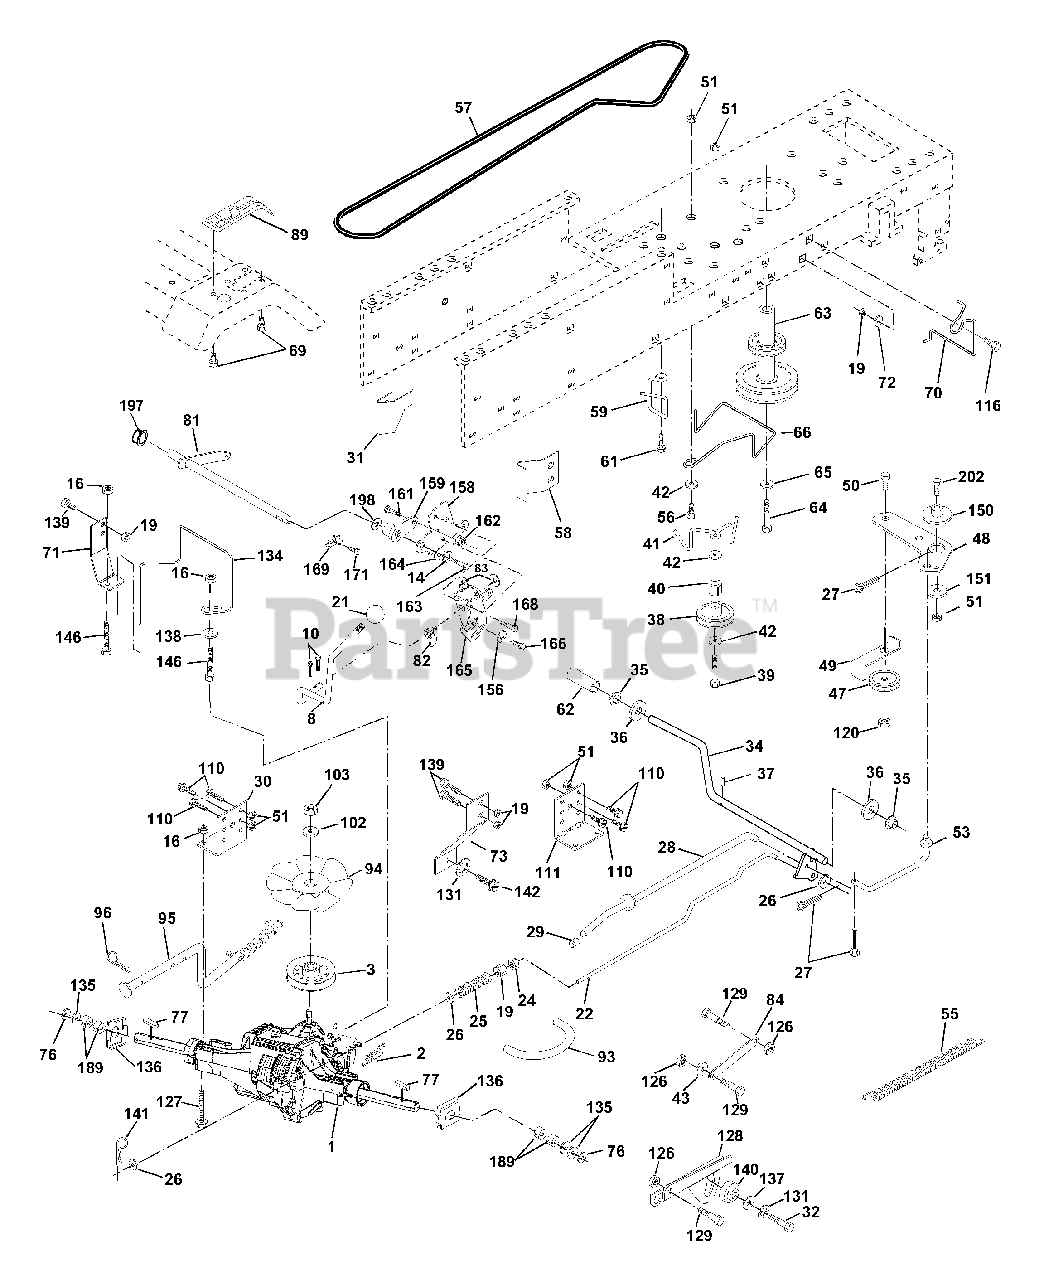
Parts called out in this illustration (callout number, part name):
2	Spring, Brake Return
3	Pulley, Hydro
8	Rod Shift Fender Adjust Yt
10	Pin, Cotter 1/8 x 1
14	Washer Lock Hvy Helical
16	Nut Lock Hx w/Ins. 5/16-18 Unc
19	Nut, Lock Hex w/Ins. 3/8-16 UNC
21	Knob
22	Rod, Brake
24	Nut, Hex Jam 3/8-16
25	Spring, Rod, Brake
26	Washer 13/32 x 13/16 x 16 Ga.
27	Pin, Cotter 1/8 x 3/4
28	Rod, Brake, Park
29	Cap, Brake Parking Black
30	Bracket, Transaxle, L.H.
31	Keeper, Belt, Transaxle, L.H.
32	Bolt Hex Hd. 5/16-18 Unc x 3/4
34	Shaft, Foot Pedal
35	Bearing Nylon
36	Washer 21/32 x 1 x 16 Gauge
37	Pin,Roll 3/16 x 1
38	Idler, Flat
39	Bolt Rdhd 3/8-16 Unc x 2-3/4
40	Spacer
41	Keeper, Idler
42	Washer 13/32 x 13/16 x 12 Gauge
43	Bolt Shoulder 5/16-18 Unc
47	Pulley, Idler
48	Bellcrank Clutch Grnd Drv Stl
49	Retainer, Belt
50	Bolt, Hex 3/8-16 x 1-1/2
51	Nut, Crownlock 3/8-16
53	Link, Clutch
55	Spring, Return, Clutch
56	Bolt, Hex 3/8-16 x 1-1/4
57	V-Belt, Drive
58	Keeper, Belt, Transaxle, R.H.
59	Keeper Belt Centerspan
61	Screw 3/8-16 x 3/4
62	Cover, Foot Pedal
63	Pulley, Engine
64	Bolt, Hex 7/16-20 x 4-1/4
65	Washer, Lock Hvy Hlcl Spr 7/16
66	Keeper Belt Engine F-proof
69	Screw Hex Wsh Hi-Lo 1/4-1/2 Unc
70	Keeper Belt Engine
71	Strap Torque Lh Hydro-3000
72	Washer 13/32 x 1-1/4 x 12 Ga.
73	Strap Torque Rh Hydro-3000
76	E-Ring
77	Key Square 1/4 x 2
81	Shaft Asm Cross Tapered
82	Spring, Torsion
83	Washer 17/32 x 3/4 x 16 Gauge
84	Link Transaxle
93	Line Fuel Hydro
94	Fan Hydro
95	Control Asm Bypass Hydro-3000
96	Retainer Spring 1" Zinc/cad.
101	Washer Belliville 1/2 x 1-1/2
103	Nut Hex Jam Toplock 1/2-20 Unf
110	Bolt Hex 3/8-16 x 3/4
111	Bracket, Transaxle, R.H.
116	Bolt Rdhd Sq Neck 3/8-16 x 1/25
120	Nut Lock Flg. 3/8-16 Unc
126	Nut Lock 5/16-18 Nc Thd
127	Bolt Hex Flghd 5/16-18 x 3.0 Gr. 5
128	Bracket Neutral Adjust HG-3000
129	Bolt Shoulder 5/16-18 Unc
131	Washer Lock 5/16
134	Rod Actuator Bypass Hydro-3000
135	Washer 1-1/32 x 1-5/8 x 16 Gauge
136	Washer Axle Flange
137	Washer 11/32 x 3/4 x 12 Ga.
138	Washer 11/32 x 1.25 x 16 Ga.
139	Bolt Fin Hex 3/8-16 x 3/4
140	Bushing Pinion Sector
142	Bolt 5/16 x 24 x 1
146	Bolt Hex Flghd 5/16-18 x 2-1/4
150	Bushing Bellcrank
151	Washer 13/32 x 2 x 10 Ga.
156	Washer Srrted 5/16ID x 1.125
158	Bracket Shift Mount
159	Hub Tapered Flange Shift Lt
161	Bolt Rdhd Sqnk 1/4-20 x 3/4 Gr 5
162	Nut Crownlock 1/4-20 Unc
163	Bolt Hex Fin 1/4-20 Unc x 1 Gr 5
164	Washer 5/8 x .281 x 10 Ga
165	Bracket Pivot Lever
166	Screw 5/16-18 x 5/8
168	Bolt Shoulder 5/16-18 x .561
169	Plate Fastening Lt
171	Screw Thdrol 3/8-16 x 1/2 Ty-Tt
189	Washer Spacer Axle
197	Nyliner Snap-In 5/8" Id
198	Washer Nyl 7/8 Id x .105
202	Bolt Carr Sh 3/8-16 x 1-1/2 Gr.5
